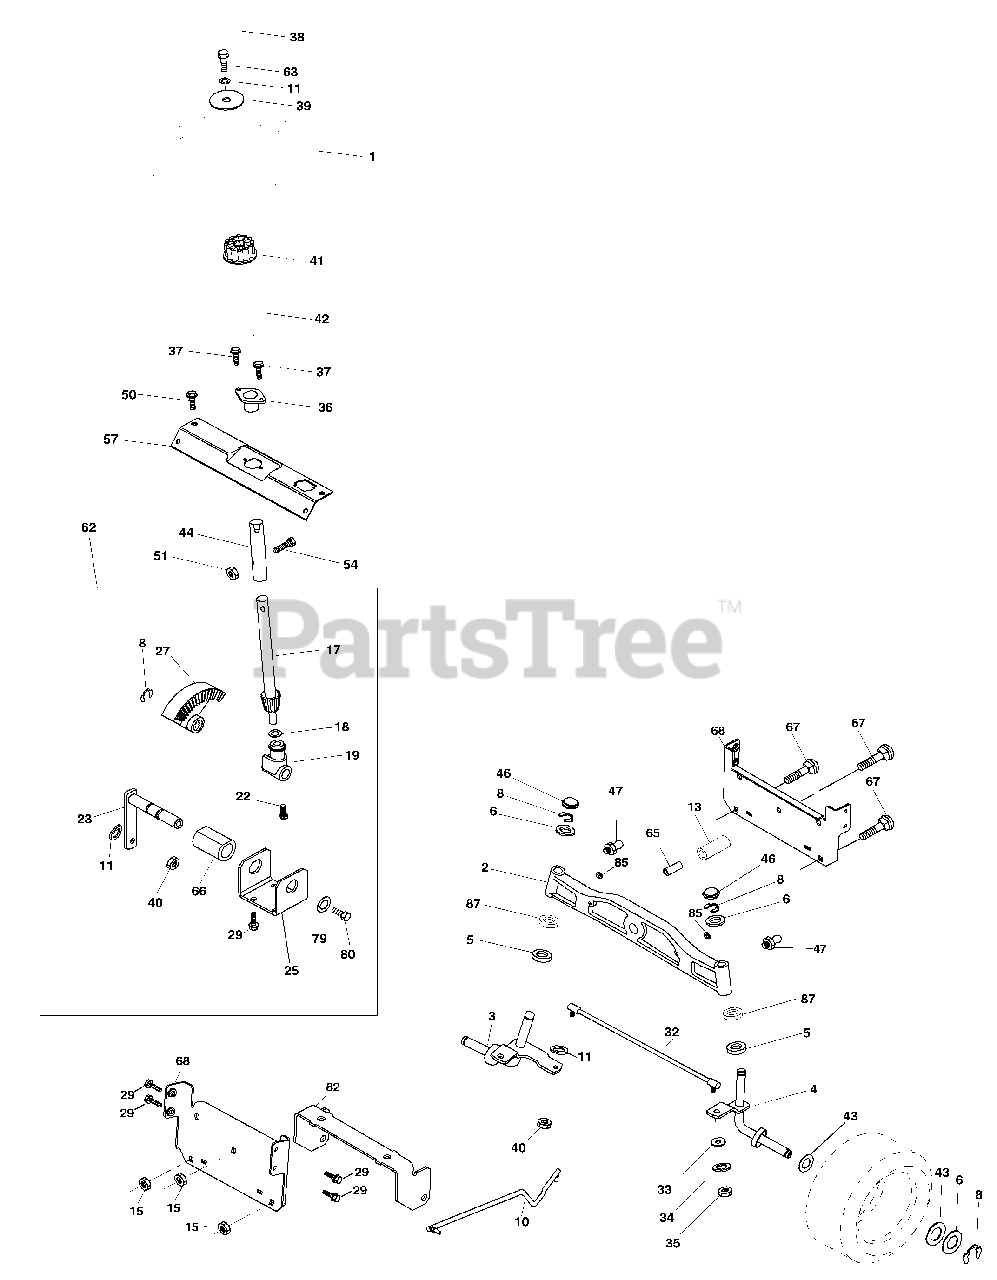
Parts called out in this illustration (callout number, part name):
1	Wheel Steering
2	Axle Asm Cast Iron LT
3	Spindle Asm LH
4	Spindle Asm RH
5	Bearing Race Thrust Harden
6	Washer 25/32 X 1-5/8 X 16 Ga
8	Ring Klip #t5304-75
10	Link Drag
11	Washer Lock Hvy Hlcl Spr 3/8
13	Spacer Brg Axle Front
15	Nut Hex Flange Lock
17	Shaft Asm Strg
18	Washer Thrust 515 x 750 x 033
19	Support Shaft
22	Screw Hex Wsh Hd Torx
23	Shaft Asm Pittman
25	Bracket Steering
27	Gear Sector
29	Screw 3/8-16 x .75
32	Rod Tie
33	Washer 11/32 x 3/4 x 16 Ga
34	Washer Lock Hvy Hlcl Spr 5/16
35	Crownlock Nut 5/16-24 Unf
36	Bushing Strg
37	Screw
38	Insert Cap Strg Wh
39	Washer 13/32 X 1-1/2 X 11 Ga
40	Lock nut
41	Adaptor Wheel Strg
42	Boot Steering Dash
43	Washer 25/32 X 1 1/4 X 16 Ga
44	Extension Steering Shaft LR/LT
46	Cap Spindle Fr Top Blk
47	Fitting Grease
51	Nut Lock Hex w/Ins 5/16-18
54	Bolt Fin Hex 5/16-18 Unc x 1-1/4
62	Kit, Steering Assembly Svc
63	Bolt Fin Hex 3/8-16unc x 1 Gr. 5
65	Spacer Brace Axle
66	Bearing Arm Pittman
67	Bolt Rdhd Sq 3/8-16 Unc x 2-3/4
68	Axle, Brace
79	Washer 13/32 x 1-1/4 x 12 Ga.
80	Bolt Hex Nylon 3/8-16 x 3/4
82	Bracket Susp Chassis Front
85	Fastner Christmas Tree
87	Washer Flat .781 x 1-1/2 x .14
